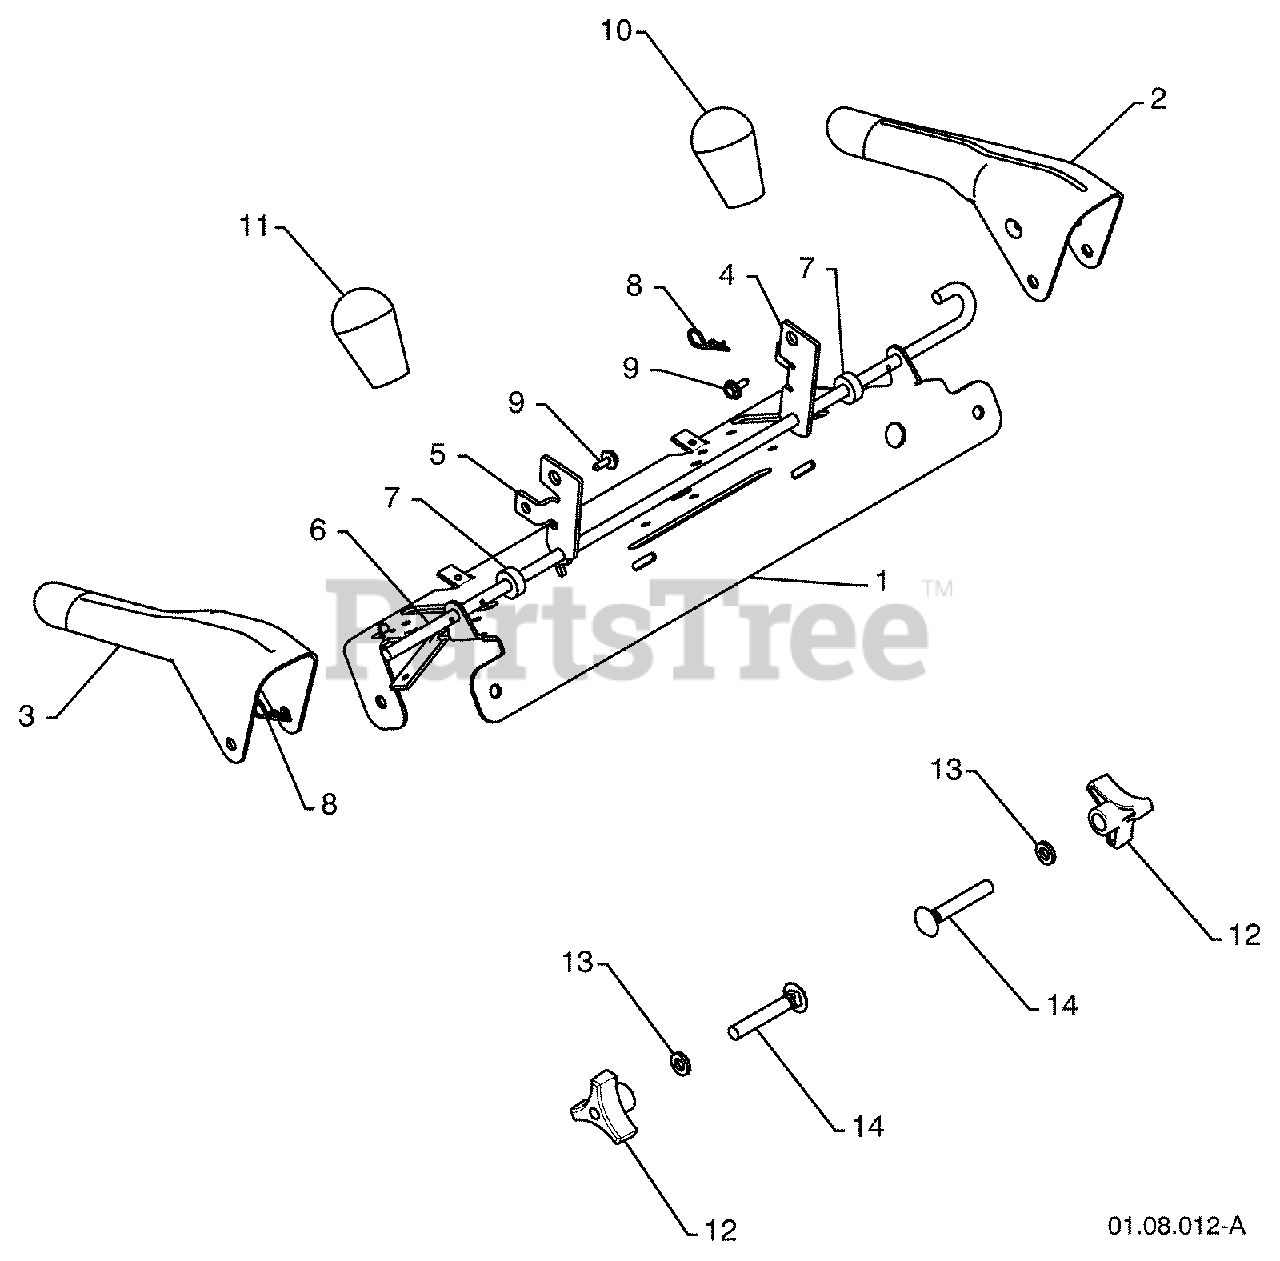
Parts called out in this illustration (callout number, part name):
1	CONTROL PANEL
2	CONTROL LEVER LH
3	CONTROL LEVER RH
4	TRACTION ROD ARM
5	IMPELLER ROD ARM
6	INTERLOCK ROD
7	SPACER CONTROL LEVER
9	SCREW 1/4-20 X .50
10	KNOB BLACK
12	HANDLE KNOB
13	WASHER 3/8
14	CARRIAGE BOLT 3/8-16 X 2.25
